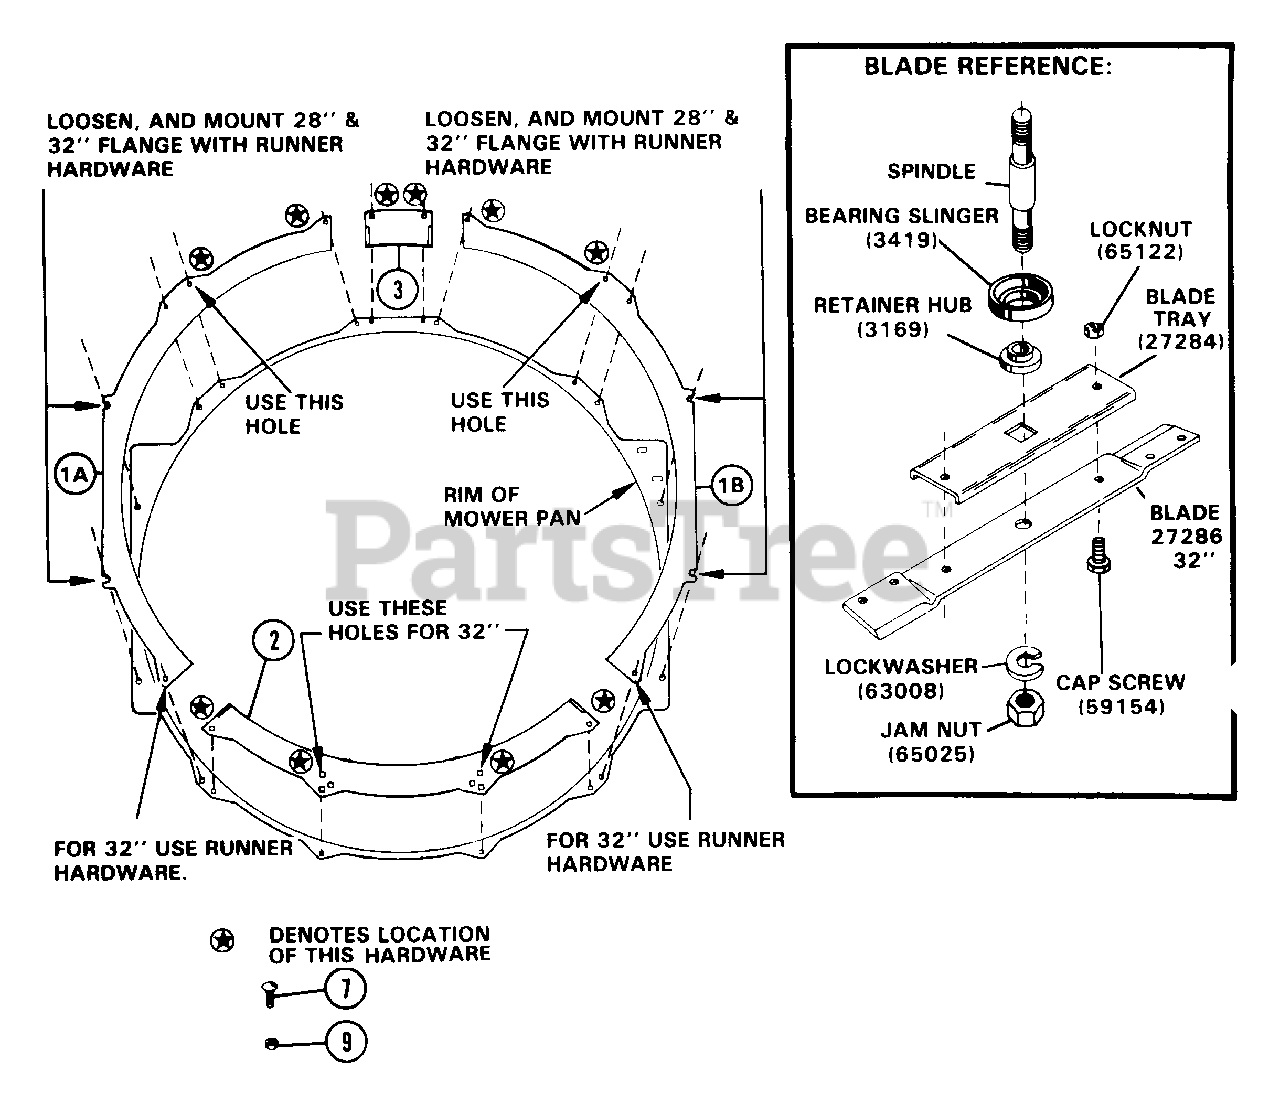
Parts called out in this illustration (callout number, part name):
1	32 IN SIDE FLANGE
2	BACK FLANGE
3	FRONT CLAMP
7	BLT-RDHDSQNK .25-20X.62 PL
9	NUT-LK-CTR .250-20 PL
10	BLT-RDHDSQNK .312-18X.62SHTPL
11	NUT-LK .312-18 GR A PL
